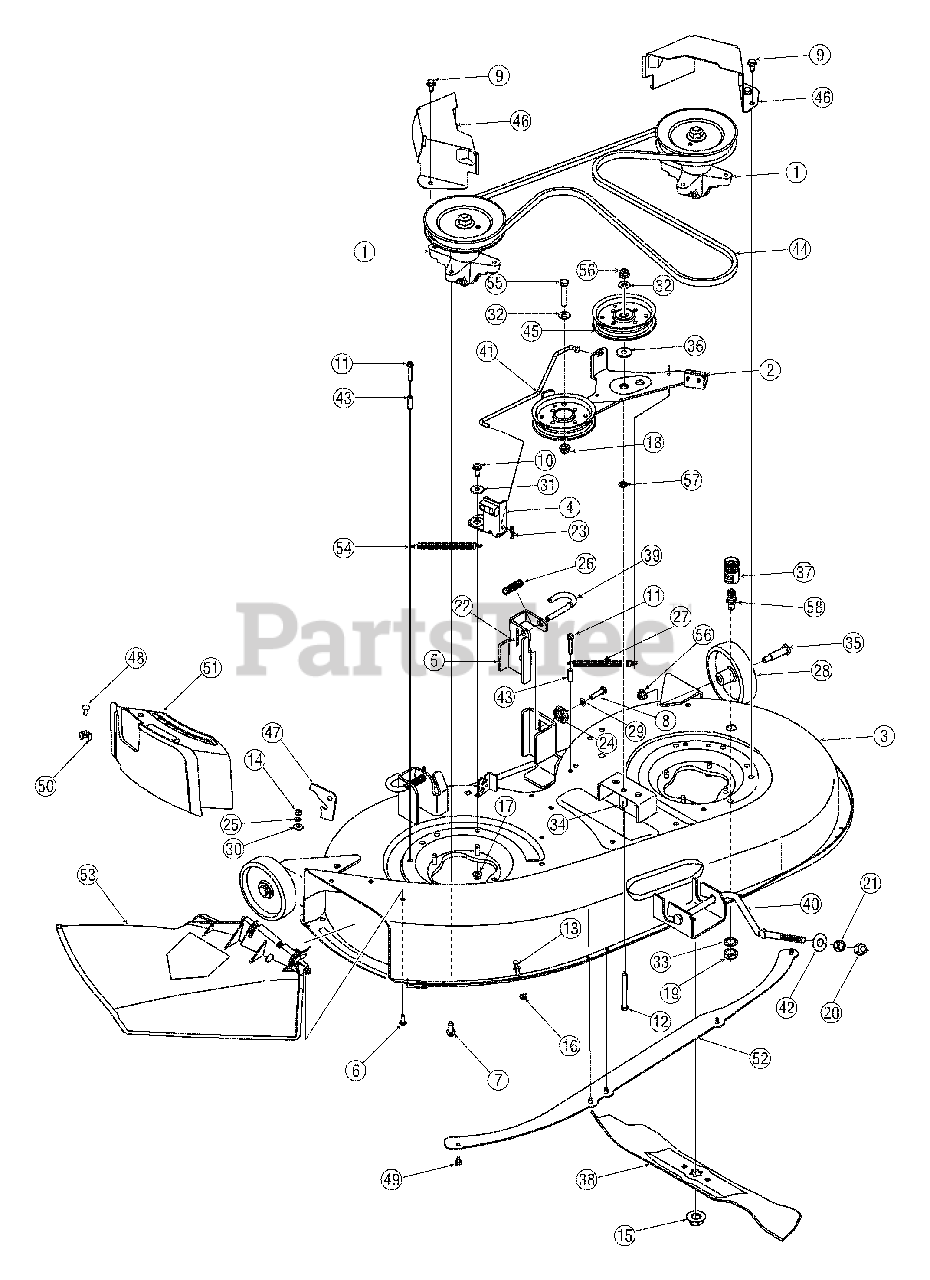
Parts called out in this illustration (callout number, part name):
1	Pulley/ Spindle Assembly
6	Screw, 1/4-20 x.620
7	Screw, 5/16-18 x.875
8	Screw, 5/16-18 x 1.25
9	Screw, 5/16-12 x.750
10	Screw, 5/16-18 x.750
11	Screw, 1/4-20 x 1.500
12	Screw, 3/8-16 x 3.50
13	Grass catcher Pin
14	Hex Nut, 1/4-20
15	Flange Nut, 5/8-18
16	Flange Lock Nut, 1/4-20
17	Flange Lock Nut, 5/16-18
18	Flange Lock Nut, 3/8-16
19	Hex Nut, M16-1.5
20	Hex Lock Nut, 1/2-13
21	Hex Nut, 1/2-13
22	Cotter Pin, 1/8 x 1.25
23	Cotter Pin,.072 Dia. x 1.13 Lg.
24	Deck Adjustment Gear
25	Push Nut,.25 ID x.50 OD
26	Compression Spring,.531 OD x 1.75 Lg.
27	Extension Spring,.50 Dia. x 6.37 Lg.
28	Deck Wheel
29	Lock Washer, 5/16
30	Bell Washer,.265 x.75 x.062
31	Shoulder Bushing,.320 ID x.135 Lg.
32	Flat Washer,.385 x.87 x.06
33	Lock Washer
34	Spacer, 3/8 ID x.68 OD x 1.46 Lg
35	Shoulder Screw,.498 x 1.53 x 3/8-16
36	Shoulder Spacer,.8540 x.200
37	Water Nozzle Adapter
38	Blade, 21.23", Star 3-in-One
39	Deck Release Handle Rod
40	Front Deck Adjustment Rod
41	Brake Control Rod
42	Deck Lift Pivot Cup
43	Spacer,.260 x.372 x 1.030 Lg.
44	V-Belt, 96.3 Lg.
45	Idler Pulley, 4.25" Dia.
47	Chute Stop
48	Carriage Screw, 1/4-20 x.62
49	Screw, 1/4-20 x.500
50	Wing Nut, 1/4-20
51	Mulch Plug
53	Discharge Chute
54	Extension Spring,.500 Dia. x 6.375 Lg
55	Screw, 3/8-16 x 2.00
56	Flange Lock Nut, 3/8-16
57	Push Nut, 3/8
58	Deck Water Nozzle
